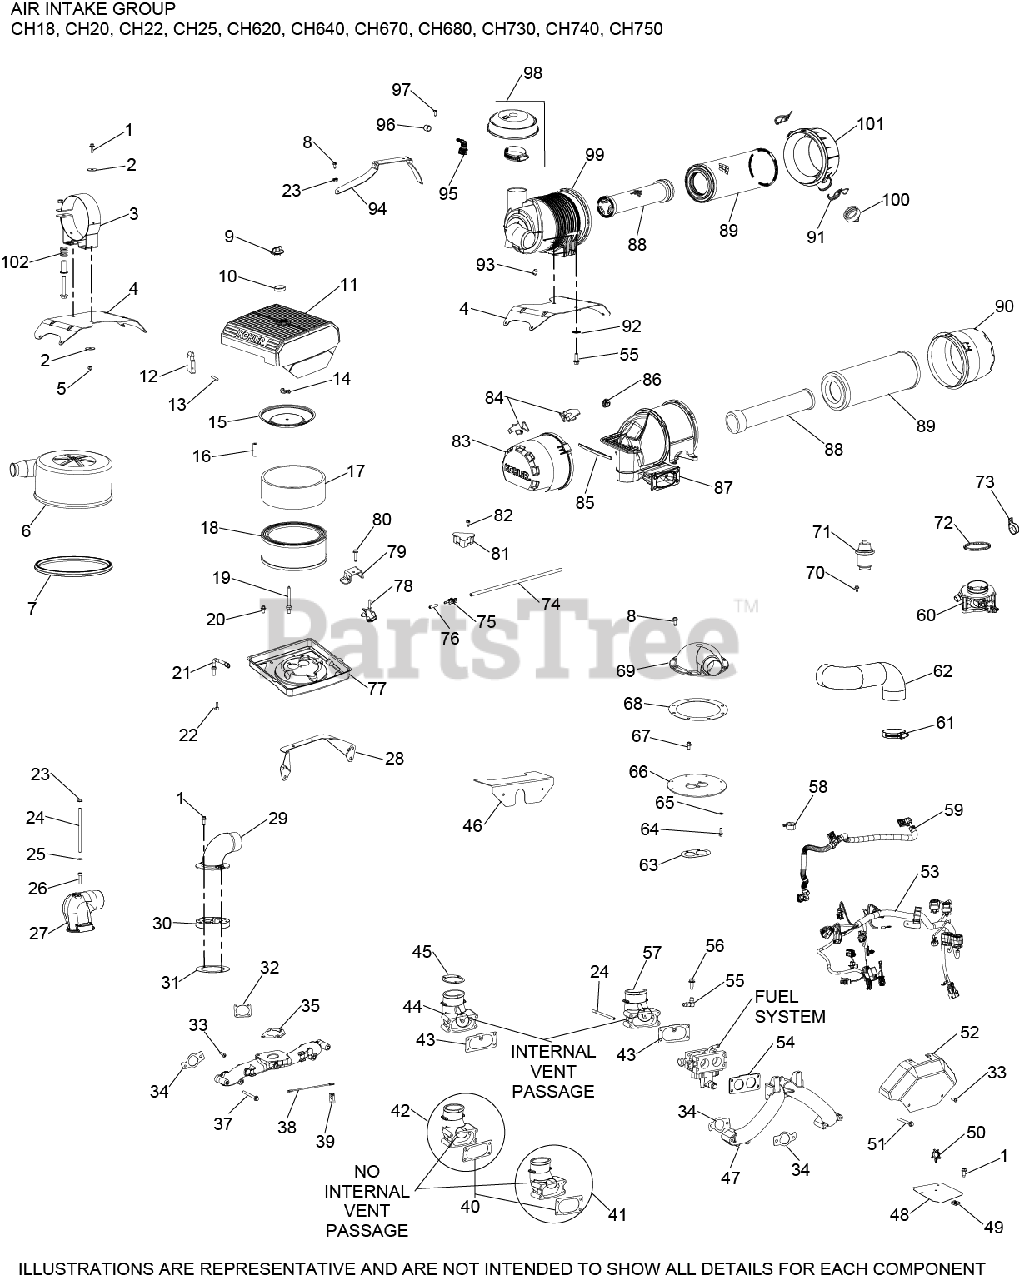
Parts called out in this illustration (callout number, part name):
6	COVER, AIR CLEANER
14	NUT, WING
15	COVER, INNER AIR CLEANER
16	SEAL, BREATHER
17	ELEMENT, PRECLEANER (LOW)
18	ELEMENT, AIR CLEANER - Also available Retail Packaged 47 883 03-S1 Air Filter Kit
18	KIT, DOME AIR CLEANER
21	HOSE, EVAPORATIVE-USE 24 326 131-S
22	CONNECTOR, EVAPORATIVE HOSE
34	GASKET, INTAKE MANIFOLD USE 24 041 79-S
35	GASKET, AIR CLEANER BASE
36	MANIFOLD, METAL INTAKE
51	SCREW, FLG M6X1.0X55
74	HOSE, EVAPORATIVE 20"
75	CONNECTOR, EVAPORATIVE
76	CAP, MASKING
79	BRACKET, AIR CLEANER
81	COVER, BLOWER HOUSING USE 24 096 160-S
82	SCREW, WSH HD TAP #8-18X1/2"
